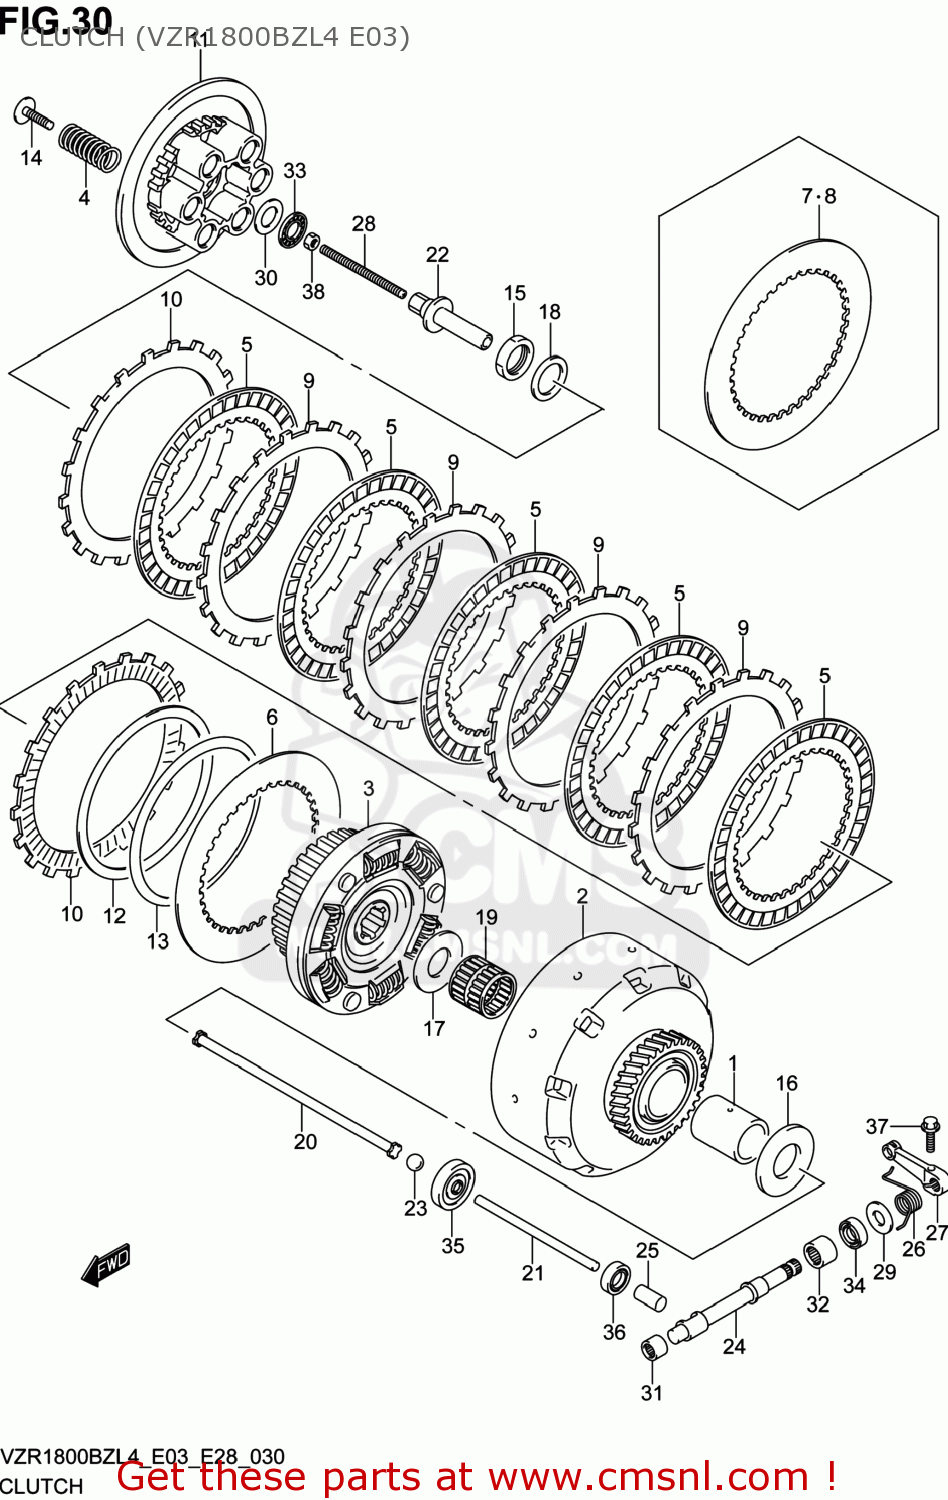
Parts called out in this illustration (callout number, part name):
1	SPACER,PRIMARY DRIVE GEAR
2	GEAR ASSY,PRIMARY DRIVE
3	HUB,CLUTCH SLEEVE
4	SPRING,CLUTCH
5	PLATE,CLUTCH DRIVE NO.1 (NAS)
6	PLATE,CLUTCH DRIVE NO.2 (NAS)
7	PLATE,CLUTCH DRIVE NO.3 (NAS)
8	PLATE,CLUTCH DRIVE NO.4 (NAS)
9	PLATE,CLUTCH DRIVEN NO.1 (NAS)
10	PLATE,CLUTCH DRIVEN NO.2 (NAS)
11	DISC,CLUTCH PRESSURE
12	SEAT,WAVE WASHER
13	WASHER,CLUTCH PLATE WAVE
14	BOLT,CLUTCH SPRING
15	NUT
16	WASHER(25X50X2.5)
17	WASHER(25X50X2.5)
18	WASHER
19	BEARING(32X37X38.3)
20	ROD,CLUTCH
21	ROD,CLUTCH PUSH,L
22	PIECE,CLUTCH PUSH
23	BALL,CLUTCH PUSH PIECE
24	CAMSHAFT,CLUTCH RELEASE
25	CAP,CLUTCH PUSH ROD
26	SPRING,CLUTCH RELEASE RETURN
27	ARM,CLUTCH RELEASE
28	SCREW(6X73)
29	WASHER(10.5X24X1)
30	WASHER(15.5X28X1)
31	BEARING(10X14X10)
32	BEARING(12X18X12)
33	BEARING(15X28X2)
34	SEAL,OIL(10X20X6)
35	SEAL,OIL(6X34X10.5)
36	SEAL,OIL(10X17X5)
37	BOLT
38	NUT
